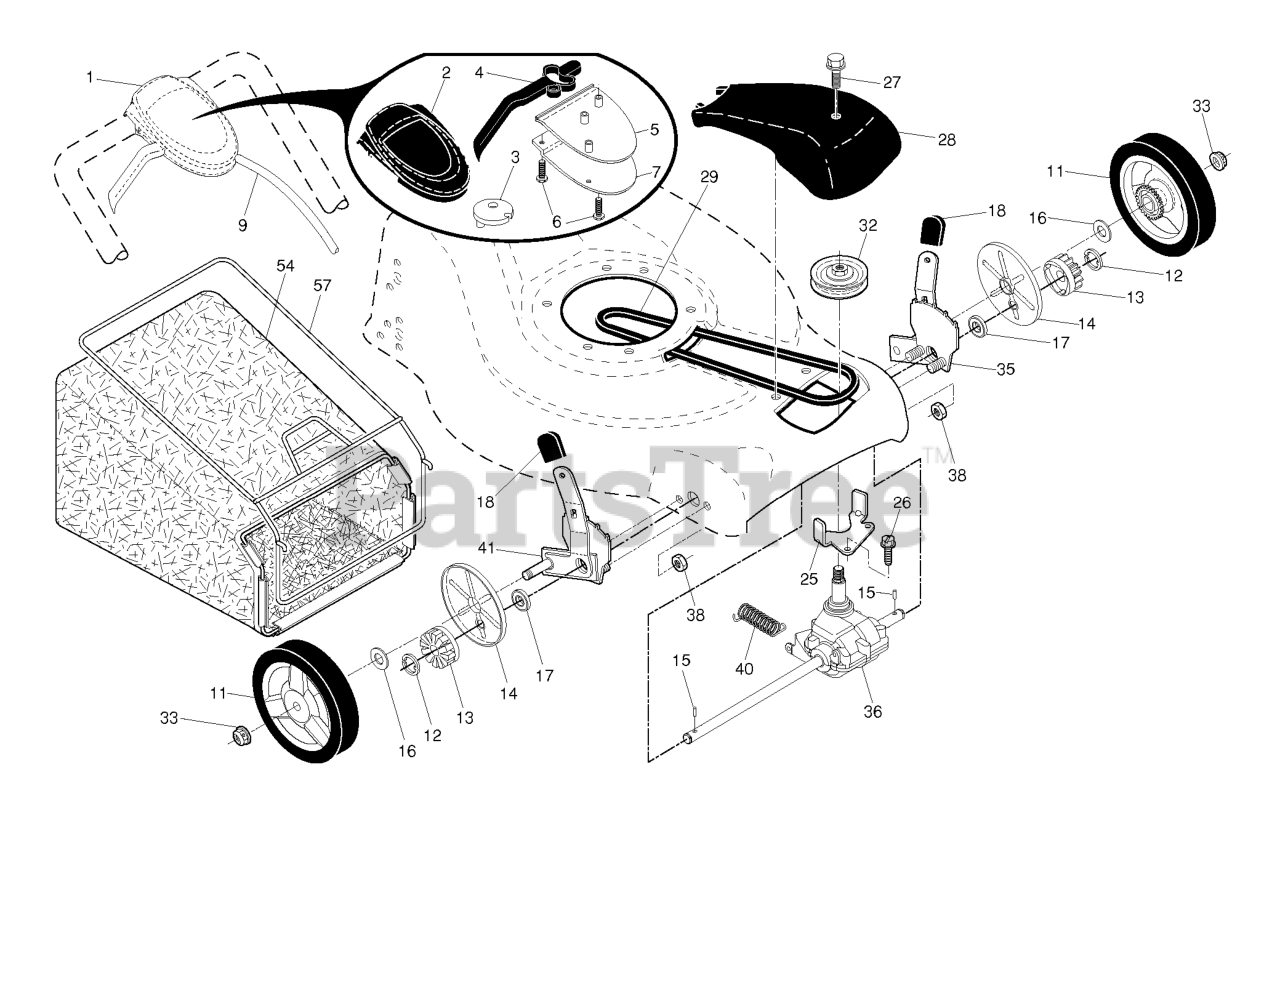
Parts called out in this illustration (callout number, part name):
1	CONTROL.DR.AW.FWGD.GRY/BLACK
2	COVER TOP AUTO WALK CONTROL
3	PULLEY.CAM.DRIVE.CONTROL.EZ
4	LEVER.SHORT.BLACK.EZ.WALK
5	COVER BOTTOM AUTO WLK CONTROL
6	SCREW, PHILLIPS HEAD 10 X 5/8
7	BRACKET.DRIVE.CONTROL.MOUNT.BL
9	CABLE ASSEMBLY, DRIVE
11	WHEEL.8X1.75.H3SPK.RAD3.GY.BU3
12	E-RING 7/16 RE
13	PINION.14.TEETH.FGD
14	COVER.DUST.WHEEL
15	PAWL, DRIVE
16	WASHER FLUT
17	BEARING
18	SELECTOR KNOB
25	BELT KEEPER
27	SCREW, HEX HD TAPPING #10-24 1
28	COVER DRIVE.21.FWGD.MOLDED GRY
29	BELT.DRIVE.FG
32	RP PULLEY.DRIVE.EZ
33	NUT.HEX.FLANGE.3/8-16.LO(3 2)
35	RP KIT, WHEEL ADJUSTER, LH
36	TRANSMISSION.21.FGD.HT.VST
38	LOCKNUT.NYLOC.1/4-20
41	KIT, WHEEL ADJUSTER, RH
54	RB GBAG.33230247T.SIL.HUSQ.BLU
57	FRAME.GBAG.21.FWGD
